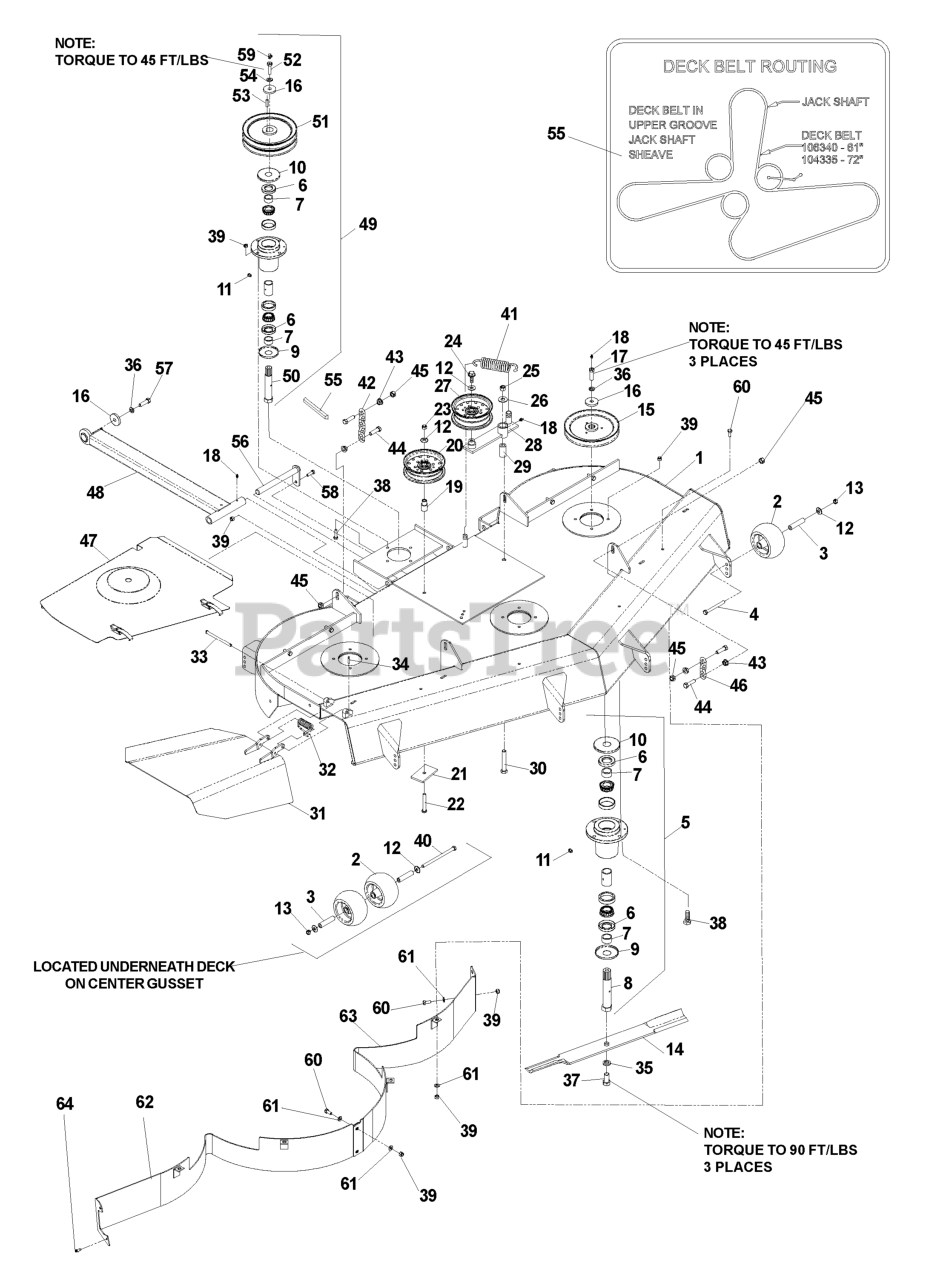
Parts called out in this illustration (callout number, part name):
1	DECK W/DECALS
2	ANTI-SCALP ROLLER
4	HCS 3/8C X 3 1/2
5	SPINDLE ASSY - 52/61"
6	SHAFT SEAL
8	SPLINED SHAFT - 72"
9	BOTTOM DUST CAP
10	TOP DUST CAP
11	PLUG-VENTED
12	WASHER 3/8 FLAT
13	NUT 3/8C CENTERBLOCK
14	BLADE OEM - 25"
15	RP PULLEY - 72"
16	SPINDLE WASHER
17	DRILLED BOLT 7/16-20 X 1 1/2"
18	ZERK
19	IDLER BUSHING
20	IDLER PULLEY
21	SUPPORT PLATE
22	SCREW 3/8C X 2 3/4 HEX CAP
23	NUT 3/8-16 NYLOC
24	4CS 3/8C X 1 SERRATED HEAD
25	NUT 1/2-13 HEX NYLOC ZD
26	WASHER 1/2 FLAT
27	IDLER PULLEY
29	PIVOT BUSHING
30	HCS 1/2C X 3 1/4
31	72 CHUTE - PAINTED
32	SPRING - TORSION
33	PIN - CLEVIS 5/16 DIA X4.69 ZD
34	RP_COTTER PIN 1/8 X 3/4
35	LOCKWASHER 5/8
36	WASHER 7/16 LOCK
37	HCS 5/8F X 1 1/4
38	HCS 5/16C X 1 1/4
39	NUT 5/16 NYLOC
40	BOLT 3/8 X 6" GRD 8
41	DECK SPRING
42	LIFT CHAIN
43	NUT 7/16C WHIZ
44	HCS 7/16C X 1 1/2
45	NUT 7/16C CENTERLOCK
46	LIFT CHAIN - 3 LINK
47	72 BELT SHIELD ASM - RH
48	STRUT WELDMENT
49	JACKSHAFT ASSY LOWER
50	JACKSHAFT SPINDLE
51	SHEAVE WSL
52	DRILLED BOLT 7/16-20 X 1 1/2"
53	KEY 1/4 SQ X 1 1/8
54	WASHER 7/16 LOCK
55	BELT, DECK
56	PIN WELDMENT
57	HCS 7/16F X 1 1/2
58	HCS 5/16C X 1
60	HCS 5/16C X 3/4
61	FLAT WASHER 5/16 SAE
62	72 FRONT BAFFLE RH WLDT
63	72 FRONT BAFFLE LH WLDT
64	HEX CAP SCREW 1/4
